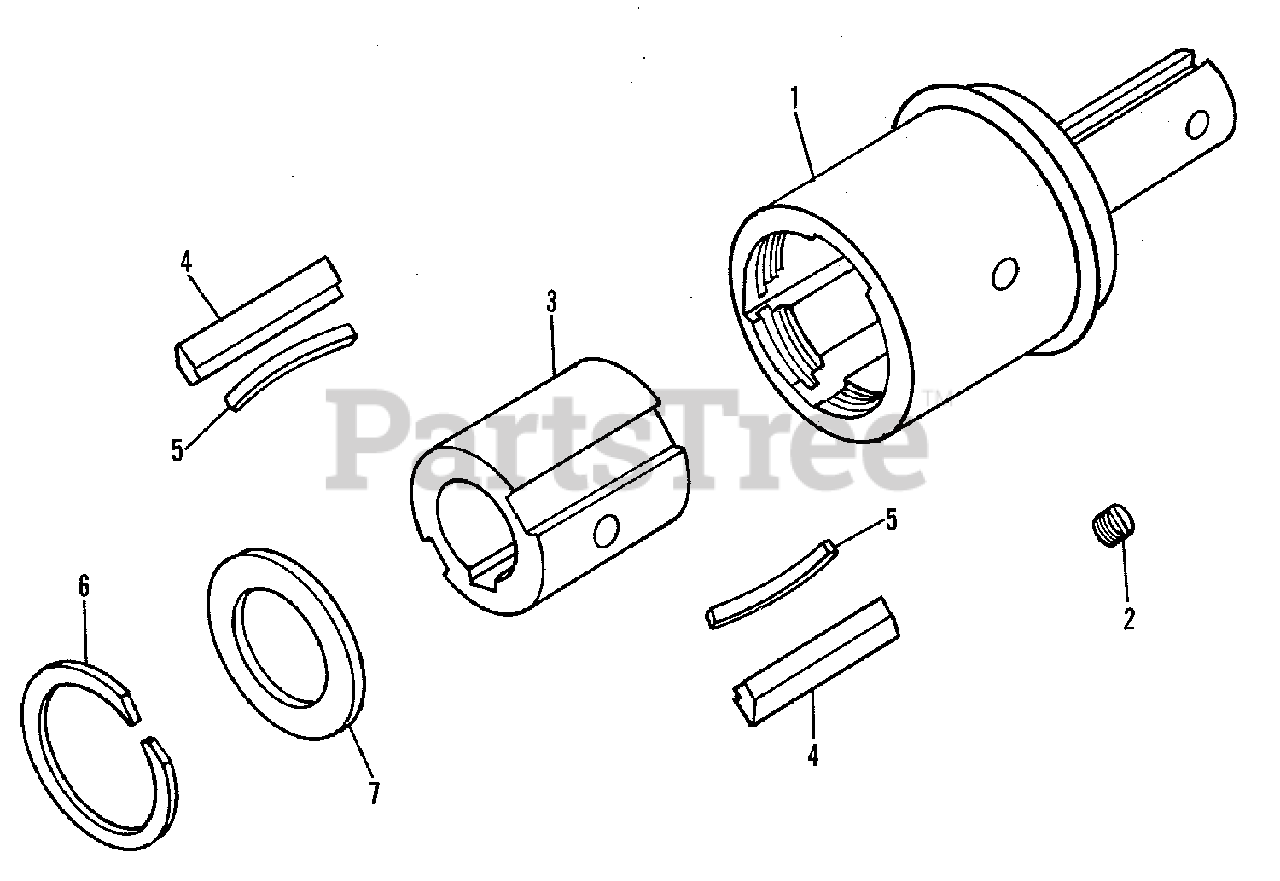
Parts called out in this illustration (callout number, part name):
1	HOUSING, Coupler
1	SETSCREW, Socket Head, Cup Point, 5/16NC x 3/4
1	FITTING, Lube, 1/8 Straight
3	SLEEVE, Drive
5	SPRING, Key
6	RING, Retaining
7	COLLAR, Retaining
